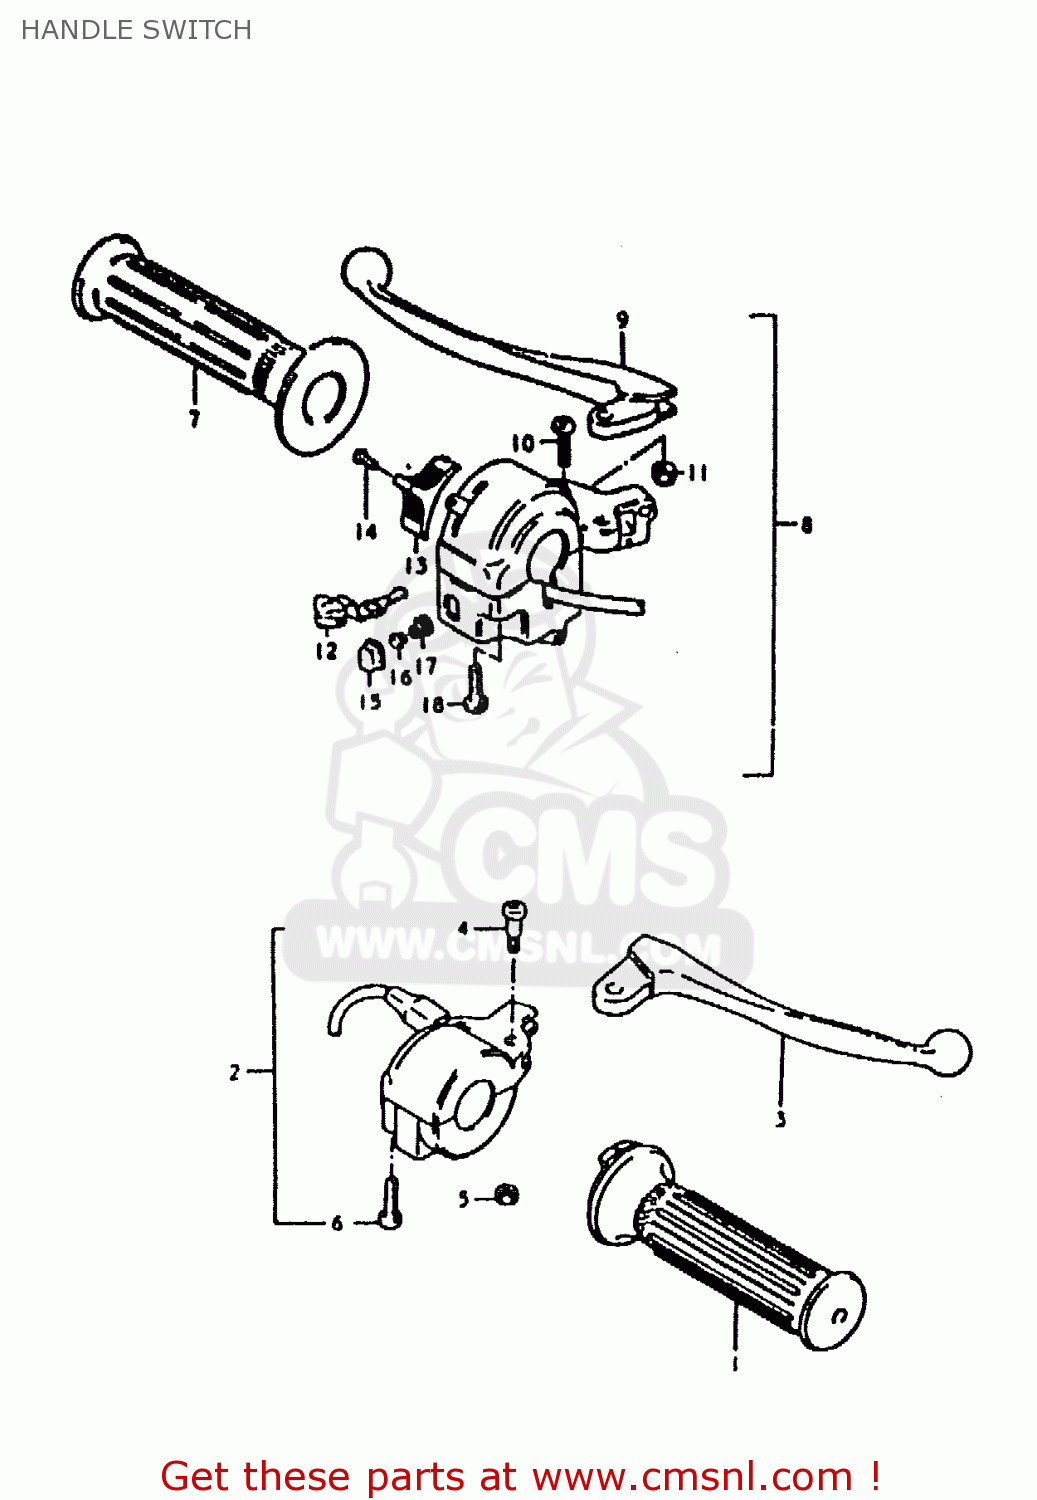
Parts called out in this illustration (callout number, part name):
1	GRIP,THROTTLE
2	BRAKE LEVER & SWITCH ASSY
3	LEVER
4	BOLT,LEVER
5	NUT,LEVER BOLT
6	SCREW
7	GRIP,L
8	LEVER ASSEMBLY
9	LEVER
10	BOLT,LEVER
11	NUT,LEVER BOLT
12	KNOB,TURN SIGNAL SWITCH
13	KNOB
14	SCREW 3X6
15	BUTTON,HORN
16	CONTACT
17	SPRING
18	SCREW
